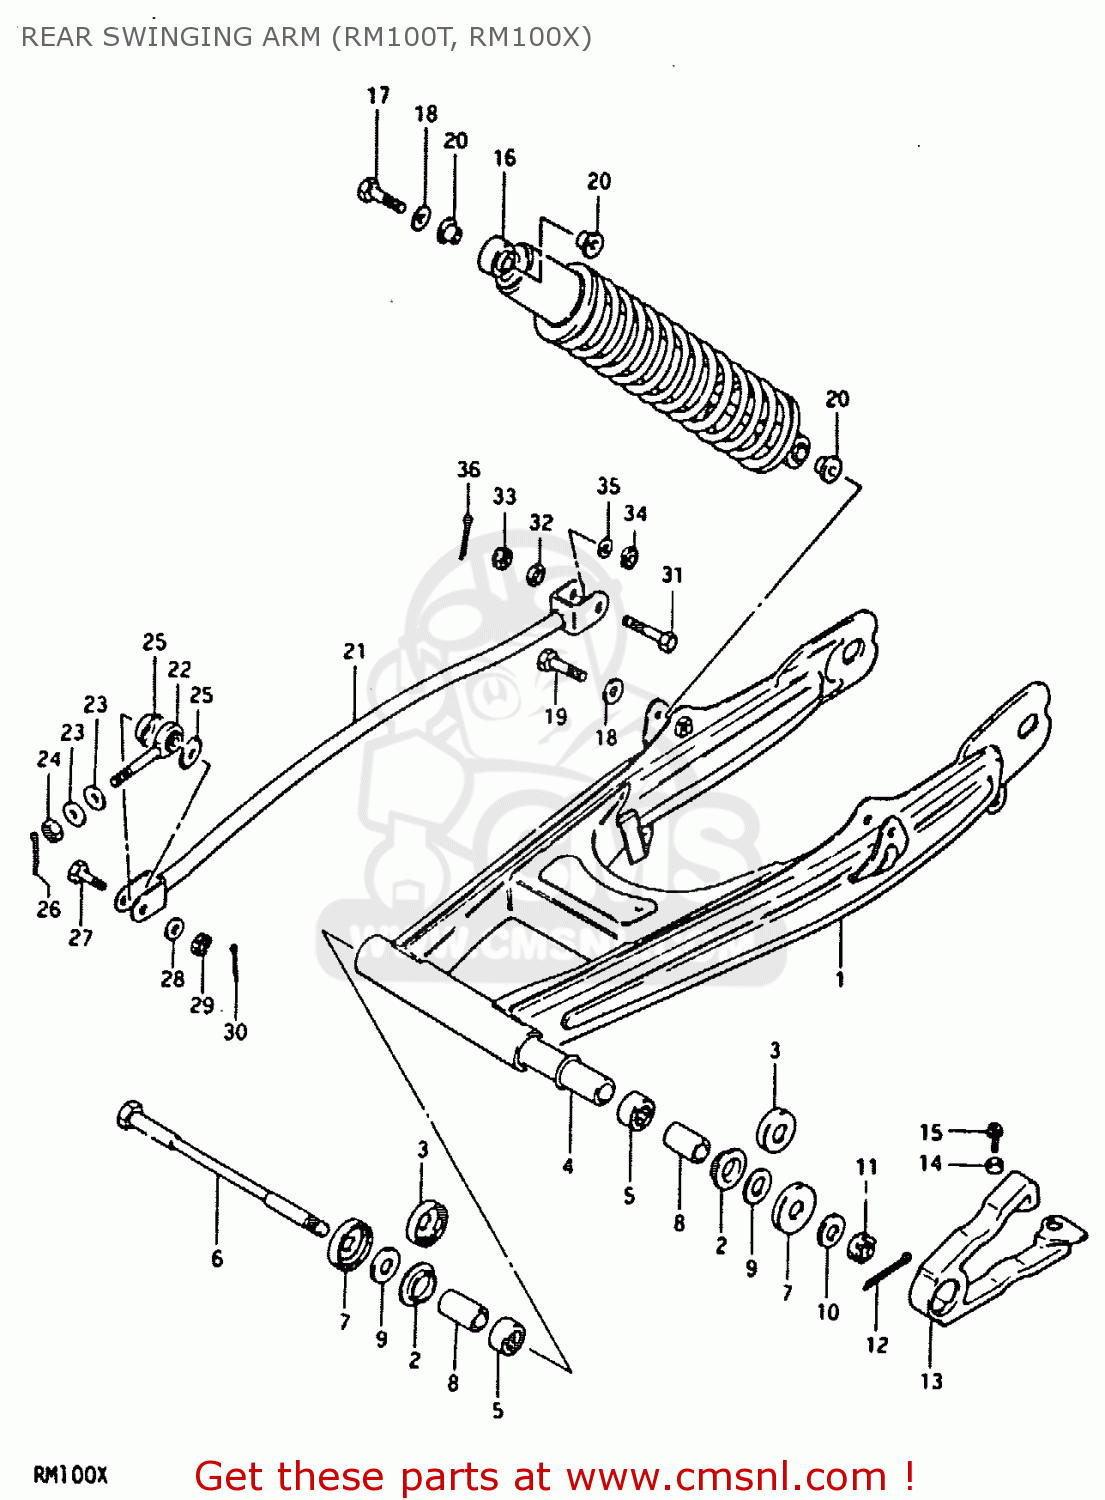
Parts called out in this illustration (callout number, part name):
1	SWING ARM ASSEMBLY,REAR
2	BUSH,RR SWINGINGARM PIVOT
3	SEAL,OIL(17X24X3)
4	SPACER
5	ROLLER BEARING (17X24X2
6	SHAFT,RR SWINGINGARM PIVOT
7	COVER,REAR SWING ARM DUST
8	SPACER,RR SWGARM PIVOT
9	WASHER
10	WASHER
11	NUT, REAR AXLE
12	COTTER PIN
13	BUFFER,CHAIN TOUCH DEFLECTOR
14	SPACER (5.5X8X4)
15	SCREW,CHAIN TOUCH DEFEND
16	ABSORBER ASSEMBLY,REAR SHOCK
17	BOLT
18	WASHER
19	BOLT
20	SPACER,RR SHK ABS INNER
21	TORQUE LINK,REAR
22	BEARING
23	WASHER
24	NUT
25	26
26	PIN
27	BOLT 8X28
28	WASHER
29	NUT 8MM
30	PIN 20X20
31	BOLT 8X35
32	WASHER
33	NUT 8MM
34	35
35	WASHER (8.5X16X2.6)
36	PIN 20X20
